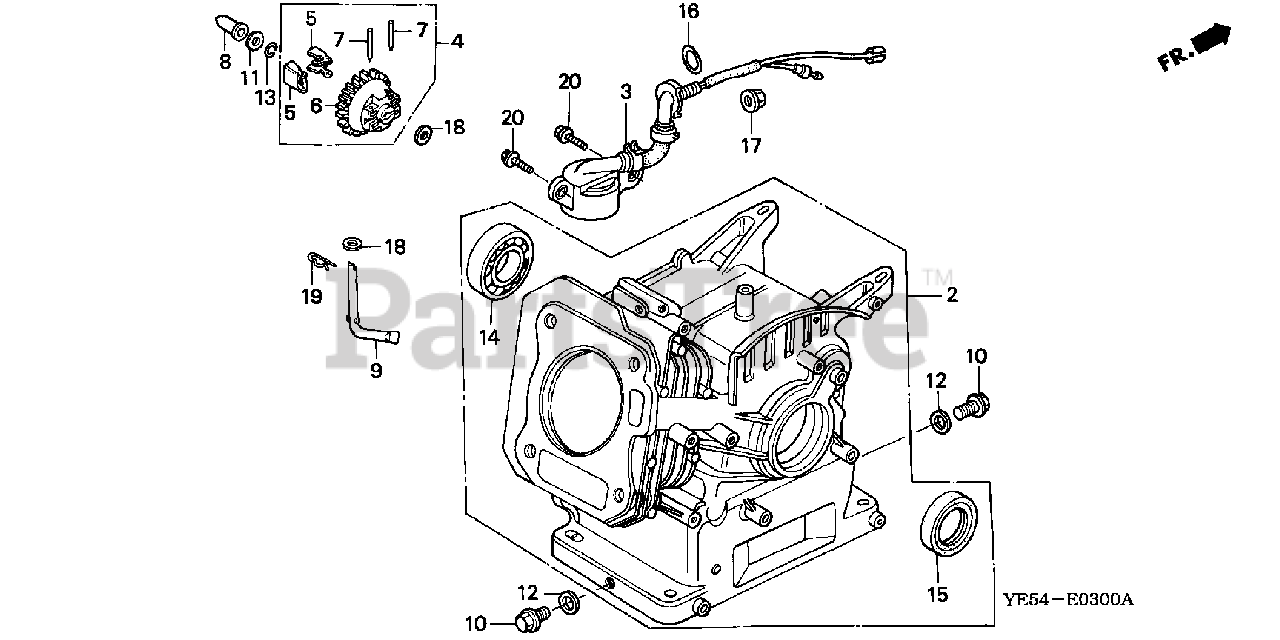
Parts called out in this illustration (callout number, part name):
2	CYLINDER ASSY. (811)
2	CYLINDER ASSY. (OIL ALERT)
3	SWITCH ASSY., OIL LEVEL
4	GOVERNOR ASSY.
5	WEIGHT, GOVERNOR
6	HOLDER, GOVERNOR WEIGHT
7	PIN, GOVERNOR WEIGHT
8	SLIDER, GOVERNOR
9	SHAFT, GOVERNOR ARM
10	BOLT, DRAIN PLUG
11	WASHER, THRUST (6MM)
12	WASHER, DRAIN PLUG (10.2MM)
13	CLIP, GOVERNOR HOLDER
14	BEARING, RADIAL BALL (6205)
15	OIL SEAL (25X41X6)
16	O-RING (13.5X1.5) (ARAI)
17	NUT, FLANGE (10MM)
18	WASHER, PLAIN (6MM)
19	PIN, LOCK (8MM)
20	BOLT, FLANGE (6X12)
